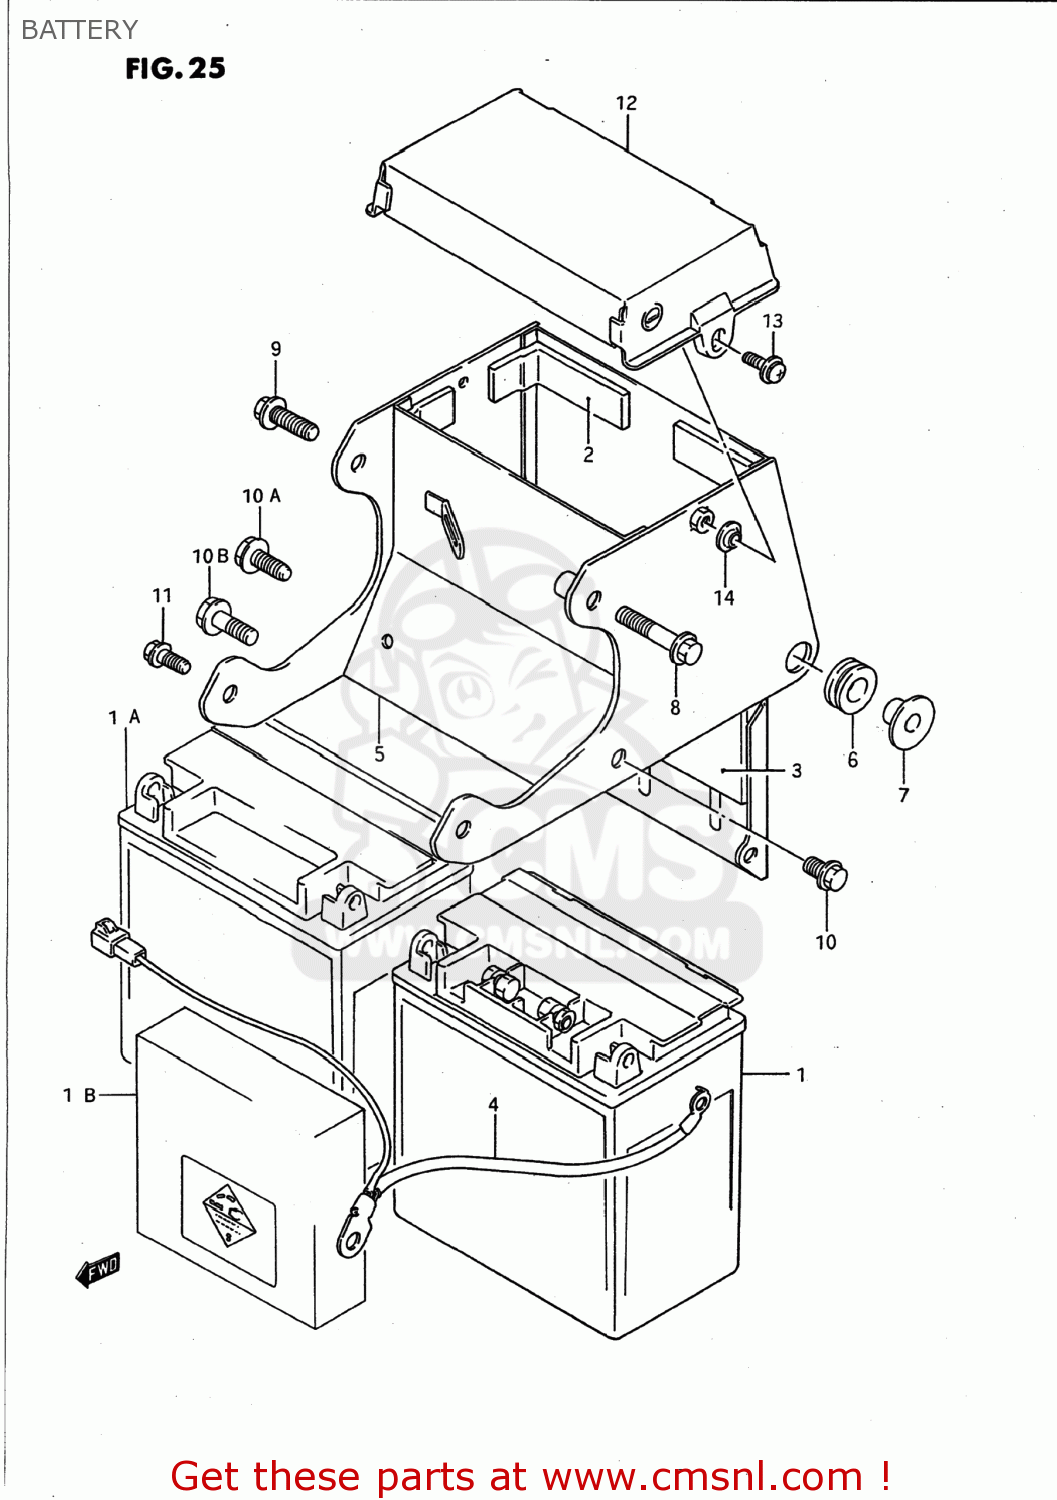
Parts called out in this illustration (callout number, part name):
1	BATTERY ASSEMBLY
2	PROTECTOR(20X90)X2
3	PROTECTOR(170X95X3.0)
4	WIRE,BATTERY MINUS LEAD
5	HOLDER COMP,BATTERY
6	CUSHION
7	BUSH
8	BOLT(8X40)
9	BOLT
10	BOLT
10A	BOLT
10B	BOLT
11	BOLT
12	COVER,BATTERY
13	SCREW(5X12)
14	WASHER
